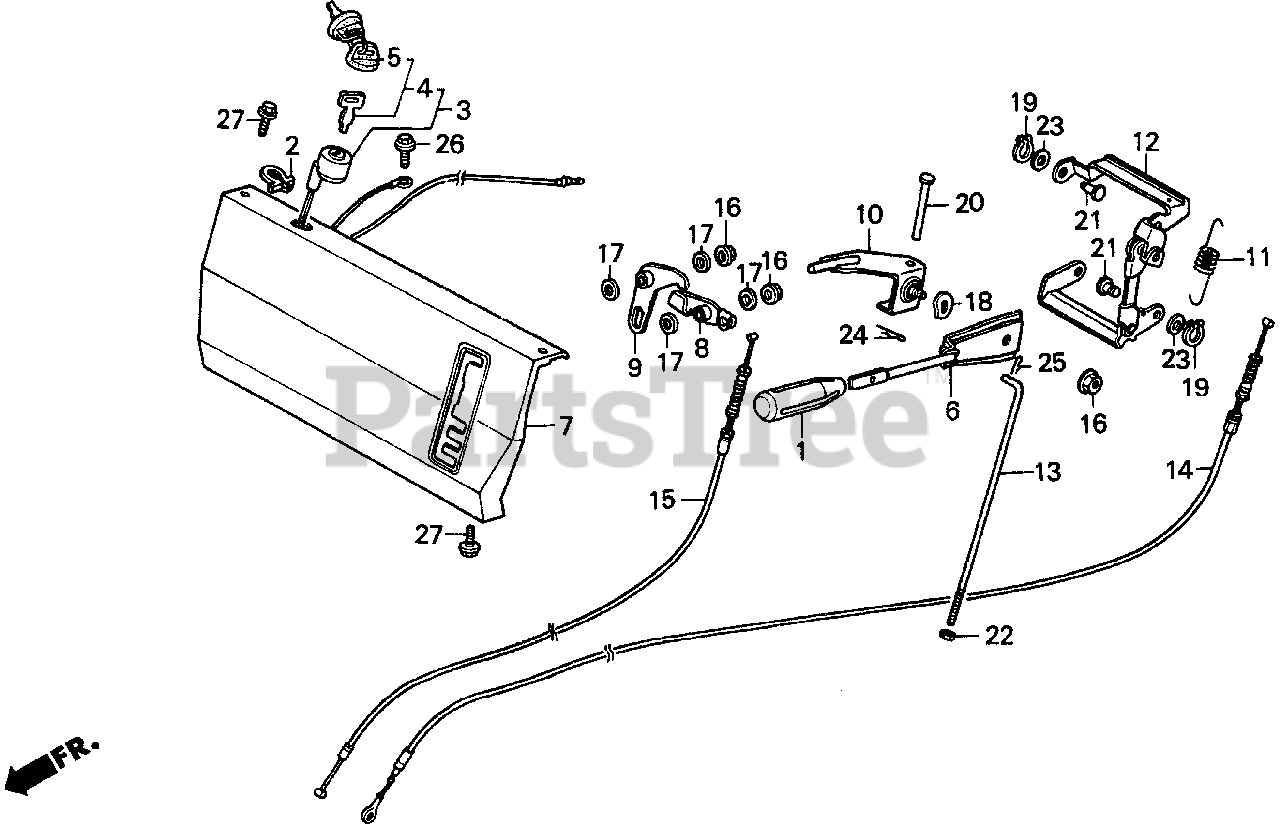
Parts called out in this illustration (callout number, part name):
1	GRIP, CHANGE LEVER
2	CLIP, IGNITION WIRE (8MM)
3	SWITCH ASSY., COMBINATION
4	KEY ASSY., COMBINATION SWITCH
5	CAP, COMBINATION SWITCH KEY
6	LEVER, CHANGE (NOT AVAILABLE)
7	PANEL, CONTROL
8	LEVER, CLUTCH DRIVE
9	LEVER, CLUTCH (NOT AVAILABLE)
10	ARM, CHANGE LEVER
11	SPRING, LEVER RETURN
12	LEVER, SUB-CHANGE
13	ROD, GEARSHIFT
14	CABLE, CHANGE (NOT AVAILABLE)
15	CABLE, SUB-TRANSMISSION
16	NUT, SELF-LOCK (8MM)
17	WASHER (10MM)
18	SPRING, LEVER
19	CIRCLIP (6MM)
21	PIN (6MM)
22	NUT, HEX. (8MM)
23	WASHER, PLAIN (6MM)
24	PIN, LOCK (6MM)
25	PIN, LOCK (8MM)
26	BOLT, FLANGE (6X12)
27	BOLT, FLANGE (6X10)
